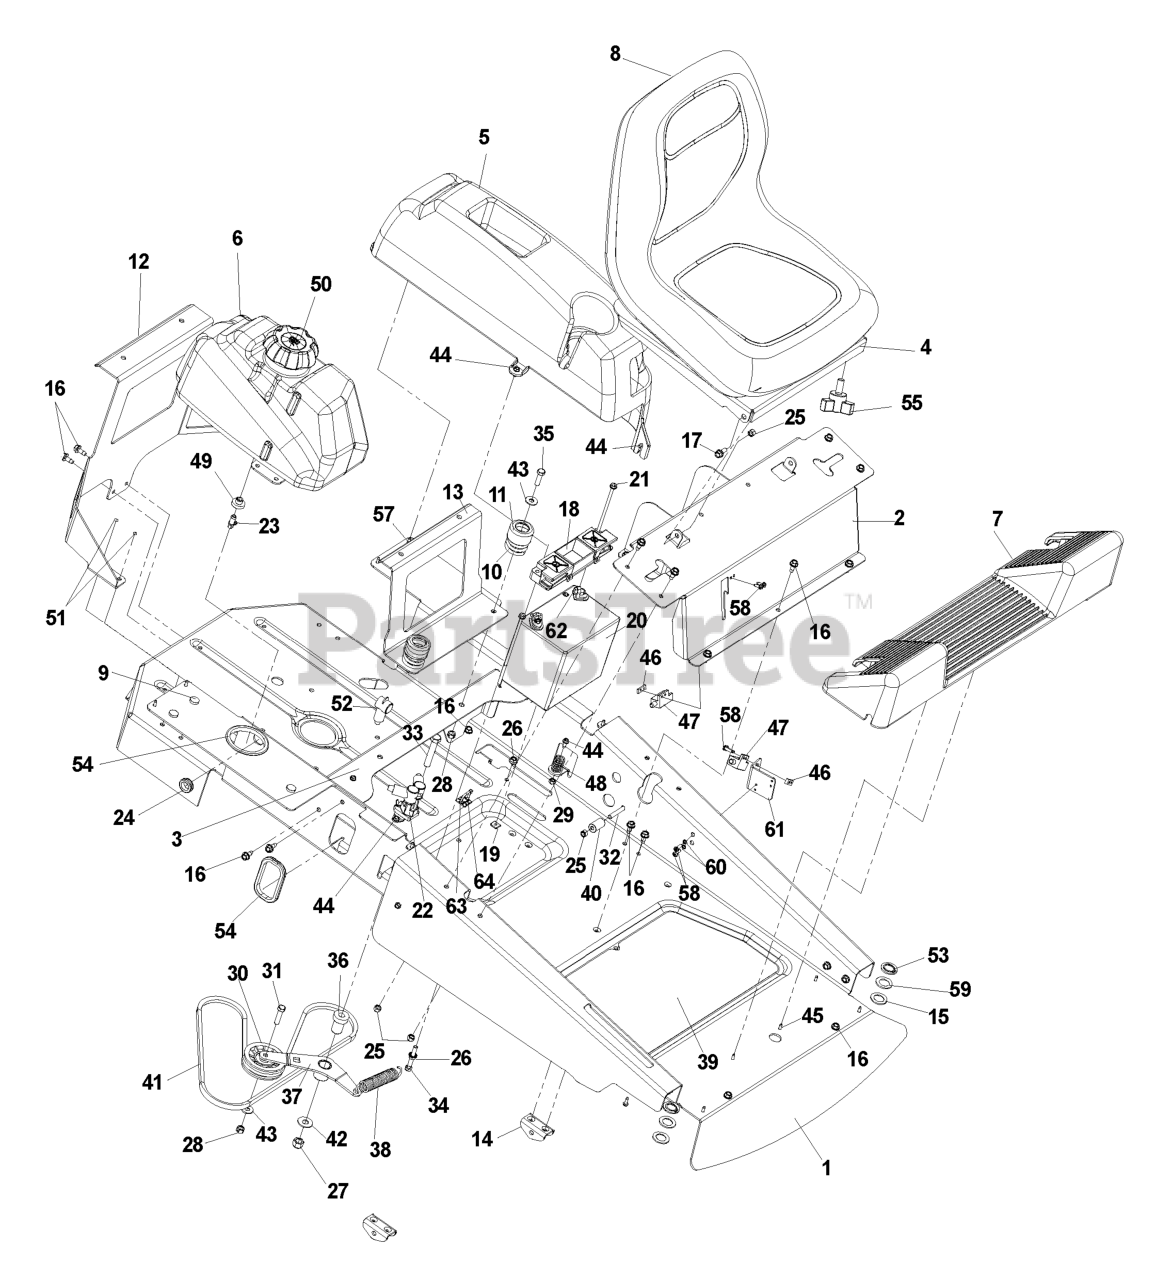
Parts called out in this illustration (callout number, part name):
1	FRAME CHASSIS
2	CONSOLE
3	REAR SEAT SUPPORT ORANGE
4	SEAT PLATE PAINTED
5	FENDER LEFT
7	FOOT REST GRAY
8	SEAT
9	GROMMET, BUMPER
10	SPRING, SEAT
11	CAP, SPRING COVER
12	REAR BRACKET W/ DECALS
13	FRT BRACKET TOOL BOX, PAINTED
14	BRACKET, DECK HANGER
15	BSHG .875 X 1.375 X .074 ZD
16	BOLT 5/16-18 X 3/4
17	BOLT, SHOULDER
18	BATTERY HOLD DOWN
19	PUSH NUT-NYLON
20	BATTERY 12 VOLT
21	BOLT - 1/4-20 X 7.5
23	STEM, FUEL TANK
24	GROMMET, FUEL LINE
25	NUT 5/16 NYLOC
26	NUT 5/16C WHIZ
27	NUT 1/2-13 HEX NYLOC ZD
28	NUT 3/8C CENTERBLOCK
29	NUT.1/4-20.HEX.NYLOC.ZD
30	PULLEY, IDLER RAKE & ZTR
31	HCS 3/8C X 1 1/2
32	HCS 5/16-18X2
33	HCS 1/2C X 2 3/4
35	HCS 3/8C X 1 1/4 GR5
36	IDLER SPINDLE
37	PUMP IDLER WELDMENT
39	SLIP, MATTING
40	MOTION LIMITER
41	BELT, HYDRO PUMP
42	WASHER 1/2 FLAT
43	WASHER 3/8 FLAT
44	SCREW 1/4 X 5/8
45	SCR #10-12X1-1/2HEX WASH HD ZD
46	TAPPED PLATE
47	SWITCH, INTERLOCK
48	SPRING, RETURN TO NEUTRAL
49	RUBBER GROMMET
50	FUEL CAP ANTI-SPLASH
53	RETAINING RING, 7/8"
55	KNOB W/STUD
57	SCR #10-12X1-1/2HEX WASH HD ZD
58	SCREW #10-24 X 5/8
60	LOCKWASHER
62	HCS 5/16C X 3/4
63	TIE, PLASTIC
64	MOUNTING BLOCK CABLE TIE
